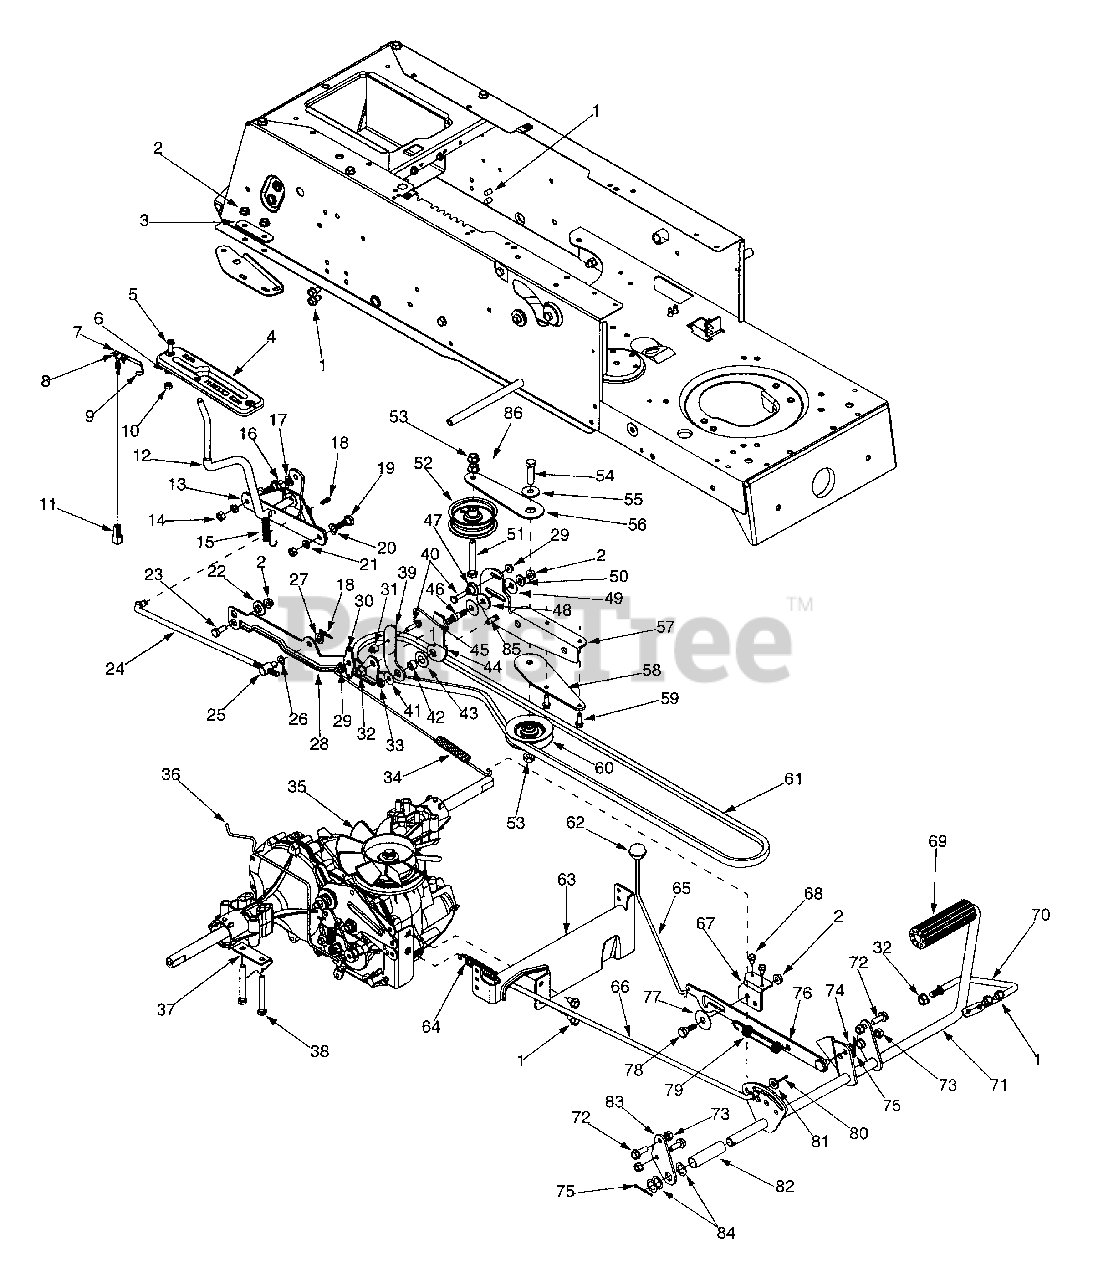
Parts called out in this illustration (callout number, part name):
1	Hex Washer Screw 5/16-18 x .625
2	Flange Lock Nut 5/16-18
4	Hydro Bracket Indicator
5	Machine Screw 1/4-20 x .75
6	Lock Washer 1/4
7	Hex Washer Screw #8-18 x .50
8	Insulator Nut Plate
9	Spring Switch
10	Hex Nut 1/4-20
11	Wire Assembly
12	Control Speed Lever Assembly
13	Speed Bracket Control
14	Hex Nut 5/16-18
15	Spring Extension
16	Hex Nut 3/8-24
17	Lock Washer 3/8
18	Cotter Pin
19	Shoulder Screw
20	Spring Washer 7/16 x .740
21	Lock Washer 5/16
22	Shoulder Spacer
23	Hex Cap Screw 5/16-18 x .75
24	Engage Rod 12.75 Lg
25	Ferrule
26	Spring Washer
27	Flat Washer .375 ID x .738 OD
30	Neutral Return Lever
31	Shoulder Spacer
32	Flange Lock Nut 3/8-16
33	Hex Lock Nut 5/16-24
34	Neutral Return Spring
35	Blade Fan
36	Hydro Bypass Rod
39	Flat Scissor
40	Hex Cap Screw 1/4-28 x 1.0
41	5/16 Washer
42	Spacer .340 ID x .560 OD
43	Flat Washer .570 ID x 1.20 OD
44	Offset Scissors
45	Neutral Return Rod
46	Friction Stud
47	Spacer
48	Friction Washer .385 ID x 1.13 OD
49	Bell Washer .39 ID x 1.13 OD
50	Flat Washer .344 ID x .750 OD
51	Hex Cap Screw 3/8-16 x 2.50
52	Flat Idler Pulley
53	Flange Lock Nut 3/8-16
54	Hex Cap Screw 3/8-16 x 1.5
55	Shoulder Spacer .625 OD
60	Idler Pulley
61	Belt
62	Ball Knob
65	Lockout Brake Rod
66	Brake Rod 22.25 Lg
67	Hydro Bracket
68	Hex Washer Screw 1/4-20 x .5
69	Foot Pad
70	Stop Rod 3/8
73	Nut 5/16-18
74	Flat Washer .385 ID x .62 OD
75	Cotter Pin
78	Shoulder Screw .437 x .286 Lg
79	Extension Spring 4.31 Lg
80	Cotter Pin
81	Flat Washer .344 ID x .750 OD
82	Spacer .640 ID x .760 OD
85	Bolt 5/16-24
86	Extension Spring .62 Dia x 6.12 Lg
